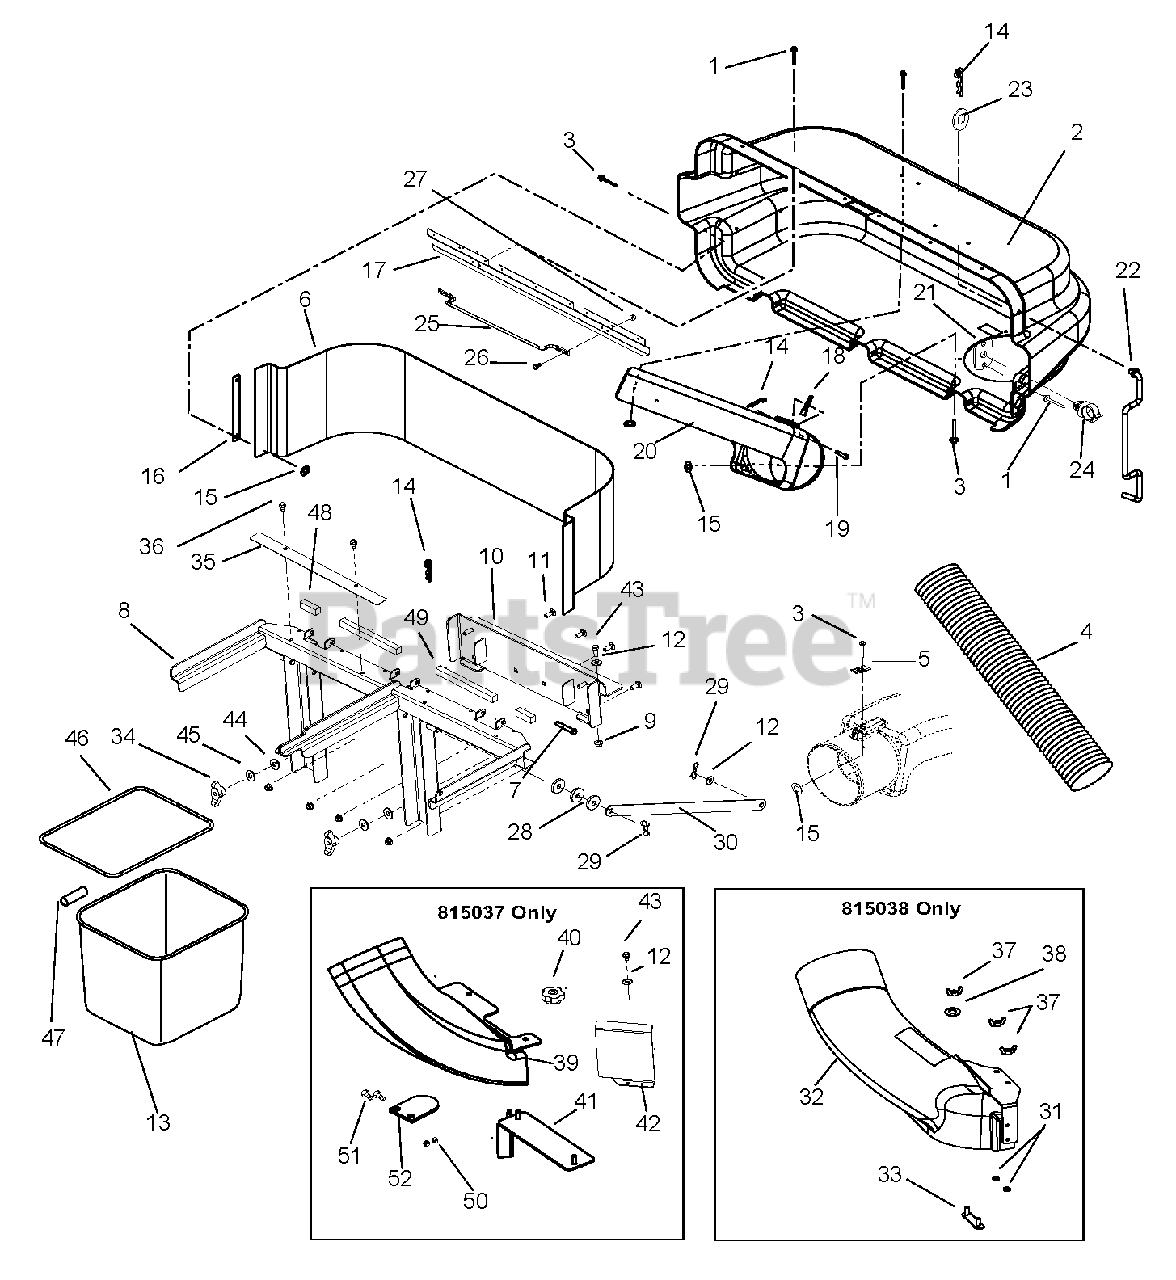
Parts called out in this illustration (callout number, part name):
1	Rivet, Pop .187 x .402
2	Cover, Bagger with Decal
3	Rivet, Pop .187 x .375
4	Hose 7 x 45
5	Thumb Latch
6	Screen, Bagger
7	Pin, Clevis .368/.373 x 3.25
8	Weldment, Bagger Frame
9	Nut, Locking Nylon Flange
10	Weldment, Mounting Plate
11	Bolt, Round Head Square Neck .38-16 x 1.00
12	Washer, Flat Steel .438 x 1.00 x .083
13	Bag, Mesh
14	Pin, Hair
15	Washer, Flat Steel .219 x .50 x .049
16	Strap, Cover
17	Latch, Cover
18	Indicator, Flow
19	Pin, Clevis .31 x 2.62 Grade 5
20	Boot, Upper
21	Plate, Rod Clip
22	Prop, Rod, Bagger
23	Washer, Flat Steel .046 x .812 x .065
24	Clip .38
25	Handle, Bagger
26	Bolt, Round Head Square Neck .25-20 x .75 Grade 5
27	Nut, Locking Top Flange .25-20
28	Washer, Flat .515 x 1.62 x .250
29	Pin, Bow Tie Locking Cotter .091 x 1.875
30	Weldment Strap, Bagger
31	Nut, Locking-Center-Jam .31-18
32	Bagger Boot Assembly
33	Weldment, Boot Mount Strap
34	Nut, Wing .375-16
35	Bracket, Bagger Overlap
36	Screw, Tapping .31-18 x .50 Hex Washer Head Thread Rolling
37	Nut, Nylock Wing .312-18
38	Washer, Flat-Steel .406 x .812 x .065
39	Bagger Boot Assembly, 34 in. Deck
40	Knob, Clamping Nyloc .312-18
41	Mount, Bagger Boot 34 in. Deck
42	Deflector, Muffler (815037 only)
43	Bolt, Hex .38-16 x 1.00
44	Washer, Flat-Steel .390 x 1.5 x .125
45	Washer, Lock 3/8
46	Bag Frame
47	Tube, Plastic 3/8 x 1/2 x 3"
48	Block Foam, 4"
49	Foam, 9.00 x 1.00 x 1.25
50	Nut, Center Locking .31-24
51	Bolt, Hex .31-24 x .75 Grade 8
52	Vane, Blade
